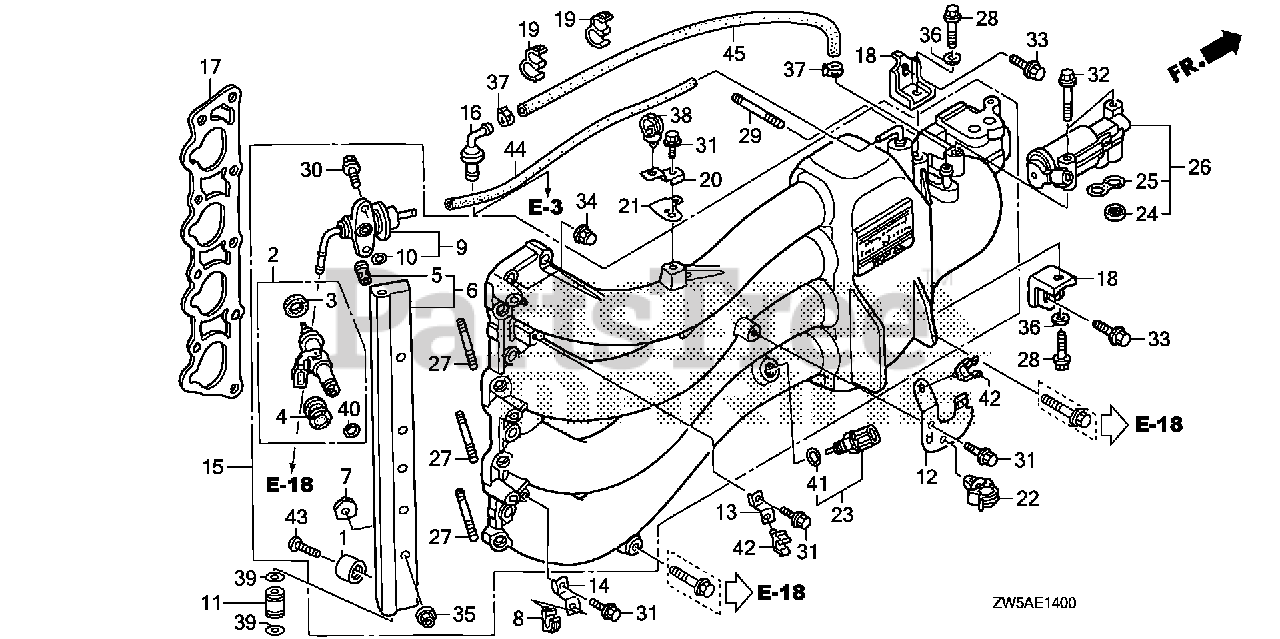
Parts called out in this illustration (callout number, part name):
1	METAL, ANODE
2	INJECTOR SET
3	SEAL RING, INJECTOR (OTSUKA)
3	SEAL RING, INJECTOR (NOK)
4	CUSHION RING, INJECTOR (NOK)
5	MESH, FUEL FILTER
6	LINE, FUEL
7	INSULATOR, FUEL PIPE
8	CLIP, TUBE
9	REGULATOR ASSY., PRESSURE
10	O-RING, PRESSURE REGULATOR
11	JOINT, FUEL PIPE
12	BRACKET, HOSE CLAMP (A)
13	BRACKET, HOSE CLAMP (B)
14	BRACKET, TUBE CLAMP
15	MANIFOLD ASSY., IN. *NH8* (DARK GRAY)
16	VALVE ASSY., PCV
17	GASKET, IN. MANIFOLD
18	STAY, IN. MANIFOLD (A)
19	CLAMP, TUBE (7.5-11.5) (BLACK)
20	BRACKET, CLIP A
21	BRACKET, CONNECTOR (D)
22	CLAMP, WIRE
23	SENSOR ASSY., AIR TEMPERATURE
24	FILTER, ELECTRONIC AIR CONTROL VALVE (TOYO ROKI)
25	GASKET, ELECTRONIC AIR CONTROL VALVE (KEIHIN)
26	VALVE ASSY., ELECTRONIC AIR CONTROL
27	BOLT 2, STUD (6X35)
28	BOLT, SPECIAL (8X16)
29	BOLT, STUD (8X35)
30	BOLT, FLANGE (6X14)
31	BOLT, FLANGE (6X12)
32	BOLT, FLANGE (8X45)
33	BOLT, FLANGE (8X18)
34	NUT, CAP (10MM)
35	NUT, FLANGE (6MM)
36	WASHER (14X23)
37	CLAMP, TUBE (D12)
38	CLIP, HARNESS
39	O-RING (7.8X1.9) (ARAI)
40	O-RING (7.3X2.2) (ARAI)
42	CLAMP, PURGE HOSE
43	SCREW, PAN (6X18)
44	BULK HOSE, FUEL (3.5X3000) (3.5X340)
45	BULK HOSE, VACUUM (7.3X1000) (7.3X370)
